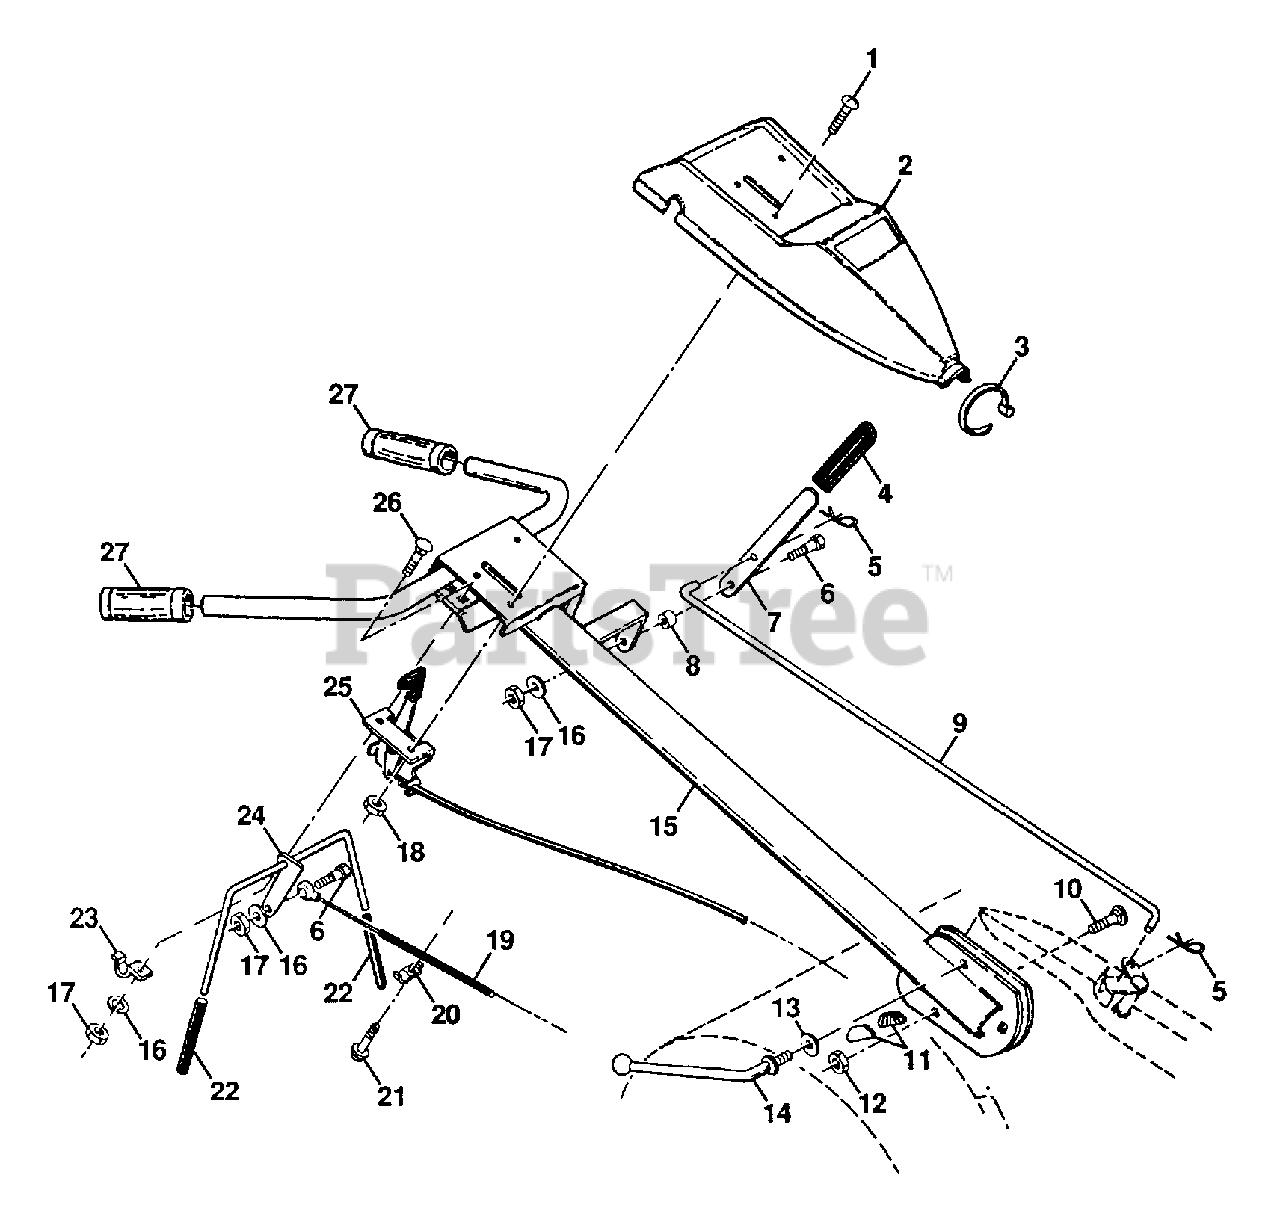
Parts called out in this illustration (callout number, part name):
1	SCREW
2	"PANEL,CONT TI"
3	TIE CABLE CRT
4	GRIP T
5	RETAINER M
6	SHOULDER BOLT ST
7	SHIFT HANDLE CRT
8	GROMMET CRT
9	SHIFT ROD CRT
10	BOLT D
11	LOCK CRT
12	LOCKNUT
13	WASHER CRT
14	LEVER LOCK CRT
16	LOCKWASHER
19	CABLE.CLUTCH.CRT
20	CONDIUT CLIP T
22	GRIP BAR CRT
24	"ASSY CONTROL, BAR"
25	"CONT,THROTTLE"
26	BOLT
